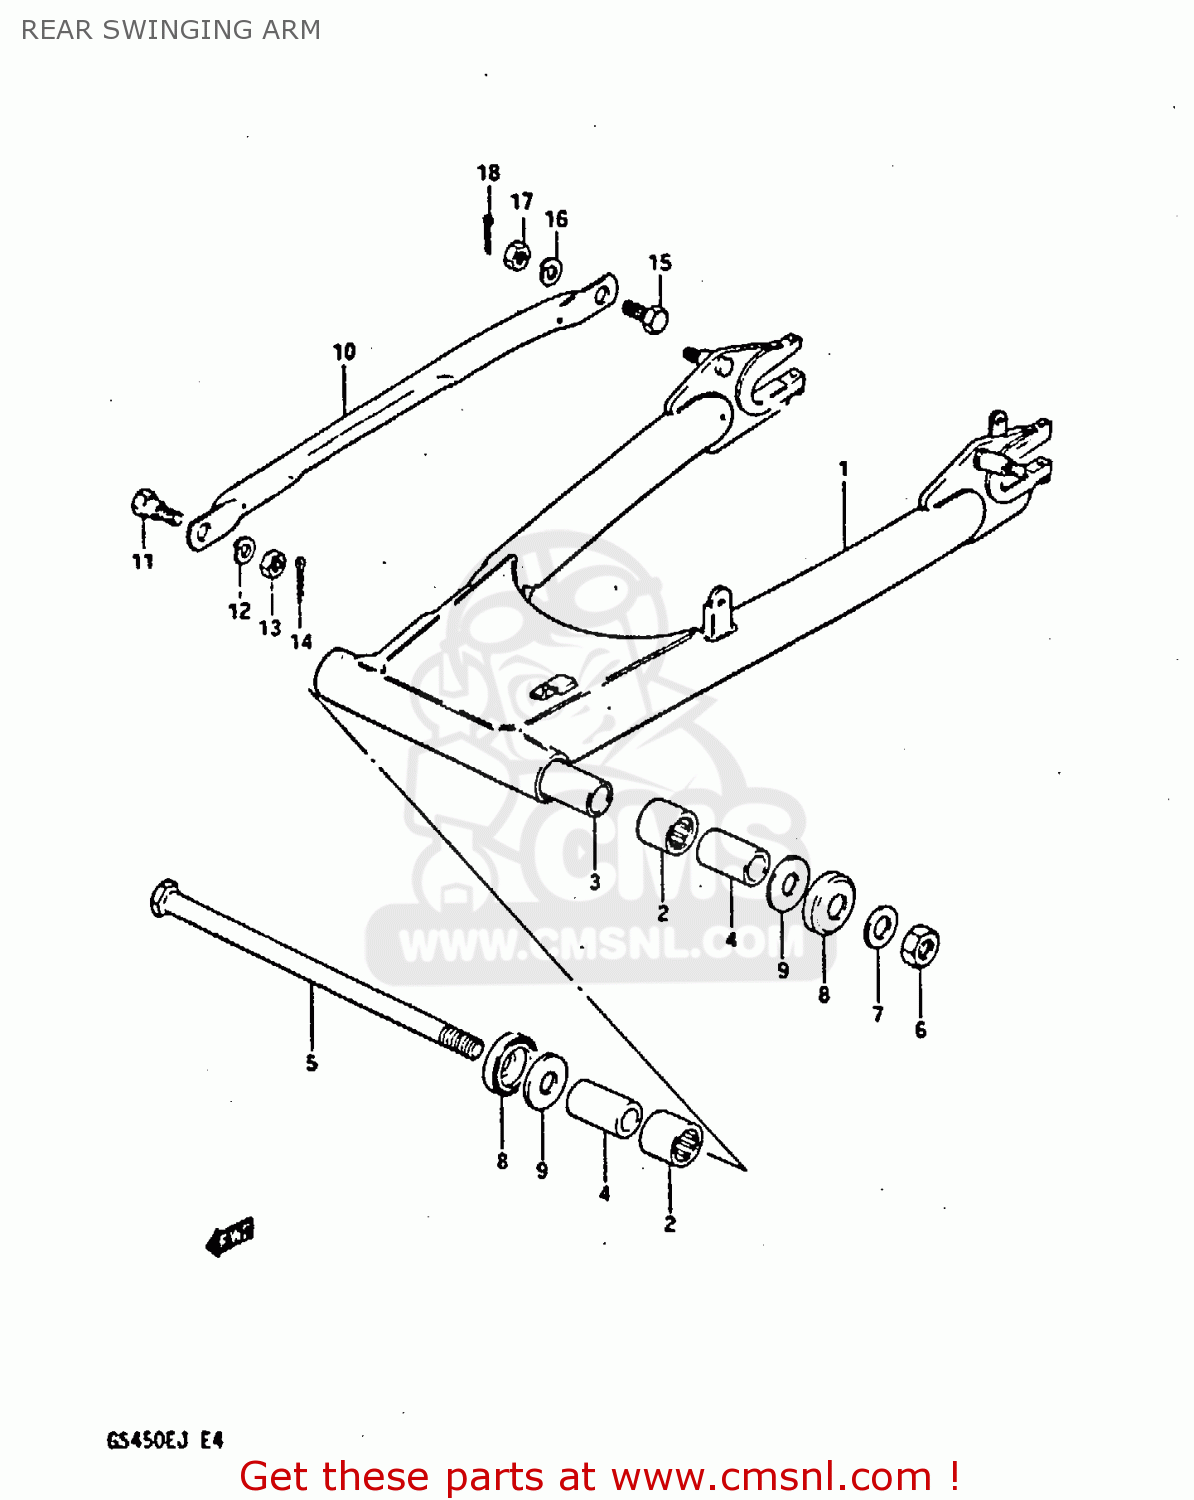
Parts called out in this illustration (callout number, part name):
1	ARM,REAR SWING
2	BEARING(22X29X30)
3	SPACER,SWINGINGARM CTR
4	SPACER,RR SWGARM PIVOT
5	SHAFT,REAR SWING ARM
6	NUT 14MM
7	WASHER
8	CVR,RR SWGARM DUST SEAL(OD:40)
9	WASHER(14.2X34X1)
10	LINK,REAR TORQUE
11	BOLT(10X24.5)
12	WASHER,LOCK,10
13	NUT
14	PIN 20X20
15	BOLT(10X31)
16	WASHER,LOCK,10
17	NUT
18	PIN 20X20
